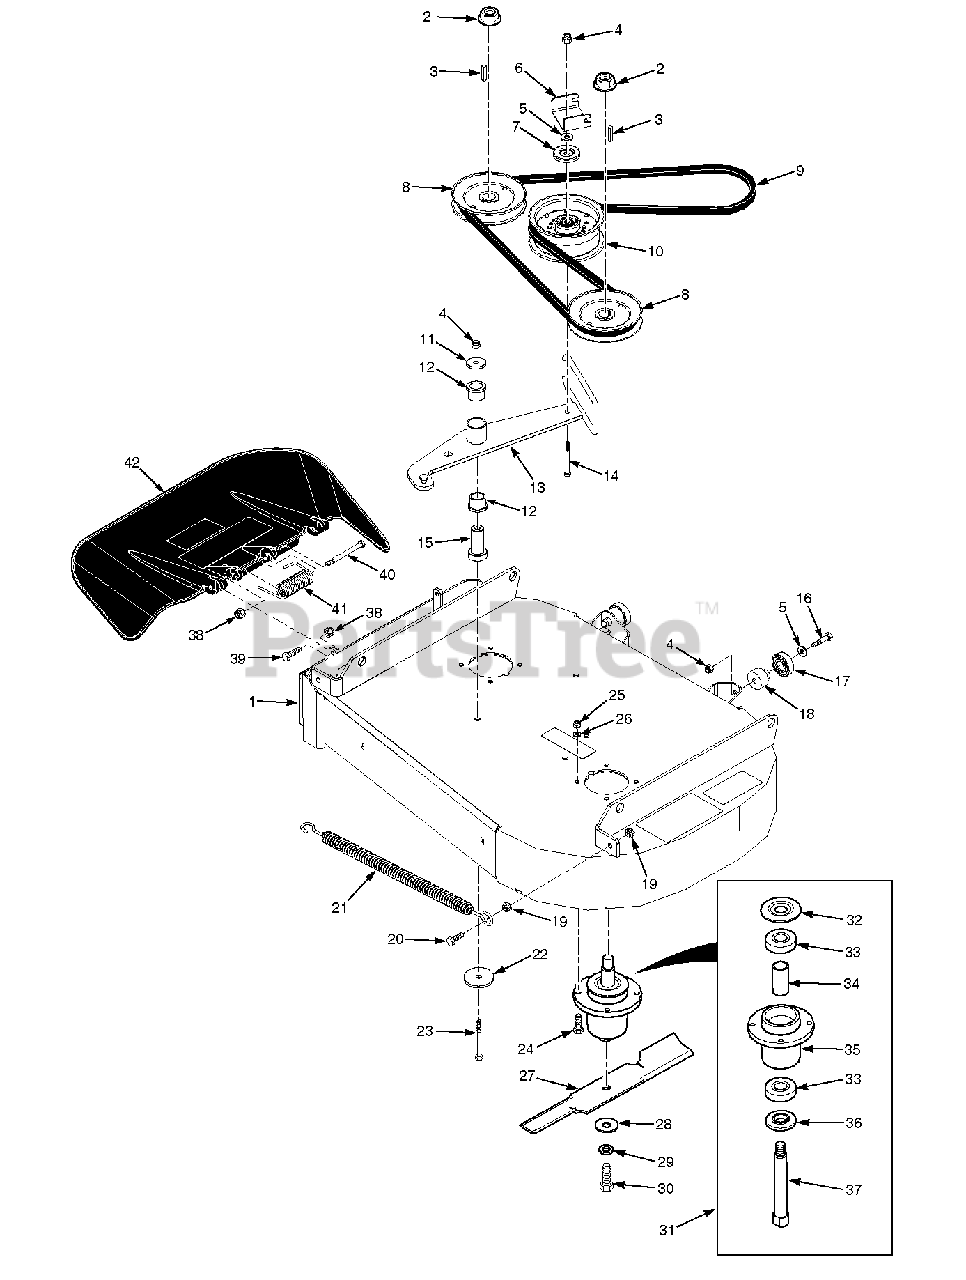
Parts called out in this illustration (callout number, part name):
1	Cutter Deck Weldment w/Decals
2	Nut, 3/4-16 Spiral Lock
3	Key, 1/4 x 1/4 x 1-1/4"
4	Nut, Elastic Stop 3/8-16
5	Flatwasher, 3/8-.391 x .938 x .105 HD
6	Bracket, Belt Guide
7	Dust Shield
8	Pulley, 5.73" Dia.
9	Belt, Deck Drive
10	Pulley, 5" Idler
11	Flatwasher, 3/8-.406 x 1-1/2"
12	Bearing
13	Idler Arm Assembly
14	Bolt, Hex Head 3/8-16 x 3-1/4"
15	Pivot, Idler
16	Bolt, Hex Head 3/8-16 x 2-1/4"
17	Bearing
18	Spacer, Bearing
19	Nut, Serrated Flange 3/8-16
20	Bolt, Hex Head 3/8-16 x 1-1/2" Gr.8
21	Spring, Deck Idler
22	Flatwasher, 3/8-.406 x 2-1/4 x .187
23	Bolt, Hex Head 3/8-16 x 3-3/4"
24	Bolt, Hex Head 5/16-18 x 1-1/2" Gr.8
25	Nut, Elastic Stop 5/16-18
26	Lockwasher, 5/16" Spring
27	Cutter Blade, 18"
28	Flatwasher, 5/8-.688 x 1-3/4 x .134 HD
29	Lockwasher, 1/2" Spring
30	Bolt, Hex Head 5/8-11 x 1-1/2"
31	Spindle Assembly
32	Debris Shield
33	Bearing
34	Spacer, Bearing
35	Spindle Housing Assembly
36	Protector, Bearing
37	Shaft, Spindle
38	Nut, Elastic Stop 5/16-18
39	Bolt, Hex Head 5/16-18 x 1-3/4"
40	Bolt, Hex Head 5/16-18 x 4-3/4"
41	Spring, Discharge Chute
42	Discharge Chute Assembly
